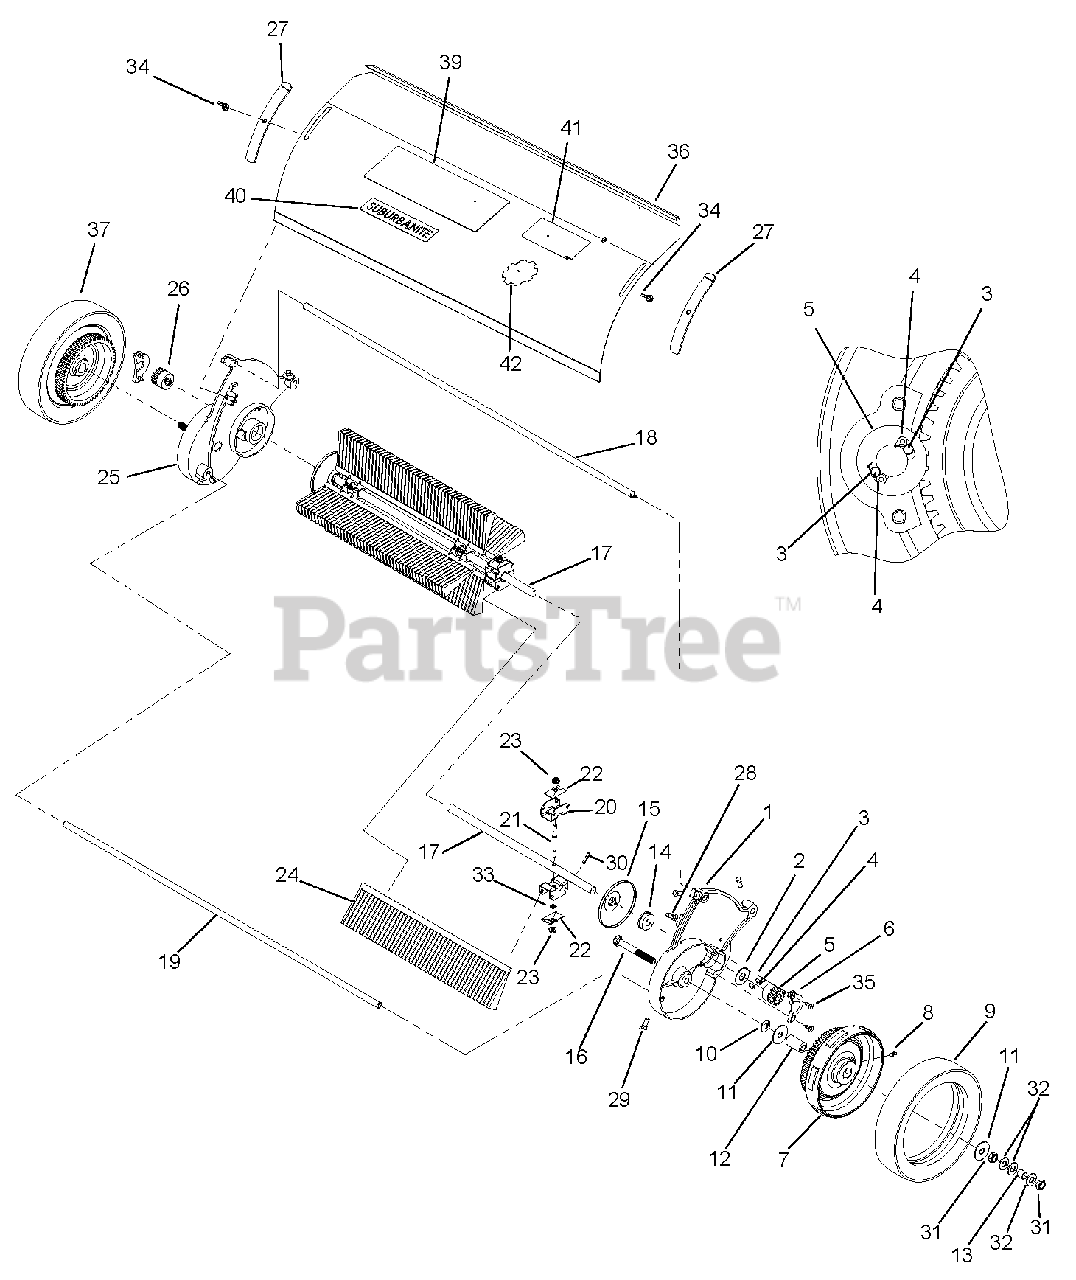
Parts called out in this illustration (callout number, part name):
11	4
23	8
24	8
28	2
29	6
31	4
32	6
